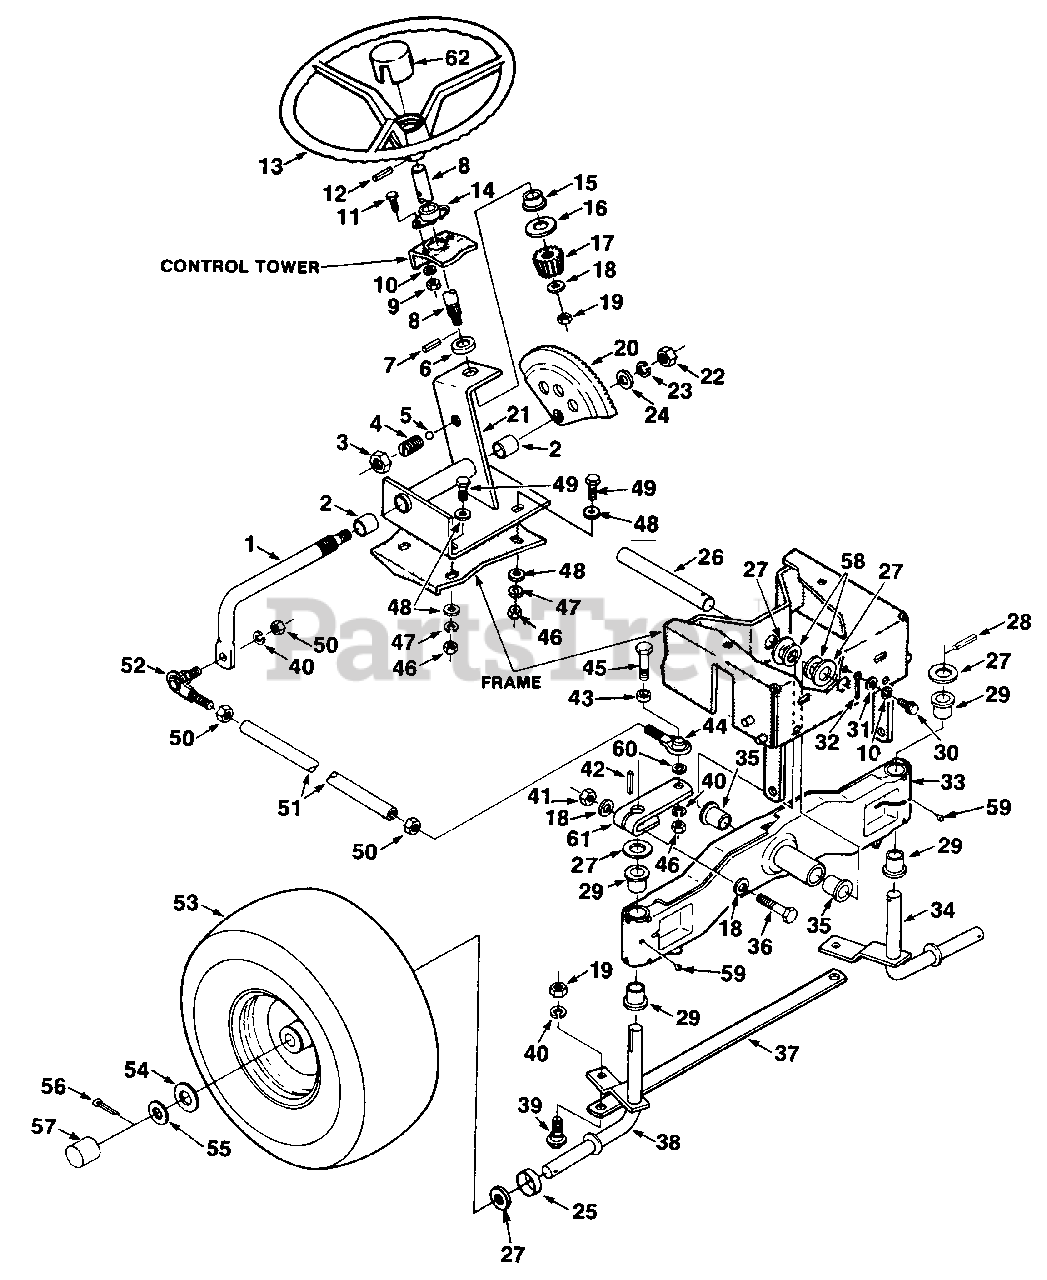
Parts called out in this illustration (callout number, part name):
1	ARM- Pitman
4	SPACER- Steering
5	BALL-.312 dia.
6	SPACER- Steering
7	PIN- Roll
8	SHAFT- Steering wheel
9	NUT- Hex 1/4-20
10	WASHER- Lock 1/4
11	SCREW- Hex 1/4-20 X 1/2
12	PIN- Roll 1/4 X 1
13	WHEEL- Steering
14	BEARING- Steering shaft
17	PINION- Steering
19	NUT- Hex 3/8-16
20	STEERING- Gear
21	SUPPORT- Steering
22	NUT- Hex 1/2-13
23	WASHER- Lock 1/2
24	WASHER- Flat 17/32
25	WASHER- Dust
27	WASHER- Flat 13/16
28	PIN- Roll 1/4 X 1 1/2
29	BUSHING- Spindle
30	SCREW- 1/4-20 X 3/4
31	WASHER- Plain 1/4
32	PIN- Cotter 1/4 X 1 1/2
33	FRONT AXLE ASSY
36	SCREW, Hex 3/8-16 X 2 1/4
39	BOLT- Tie bar mounting
40	WASHER- Lock 3/8
41	NUT- Centerlock 3/8-16
42	KEY- 3/16 X 1 1/8
43	SPACER- Ball joint
44	BALL JOINT
45	SCREW- Hex 3/8-16 X 1 3/4
46	NUT- Hex 5/16-18
47	WASHER- 5/16
48	WASHER- 5/16
49	SCREW- Hex 5/16-18 X 7/8
50	NUT- Hex 3/8-24
51	TUBE- Drag link
52	BALL JOINT
53	RIM & TIRE ASSY
55	WASHER-HT
56	PIN- Cotter 5/32 X 1 1/4
59	FITTING- Grease
60	SPACER- Ball joint
61	ARM- Steering
62	CAP- Steering wheel
